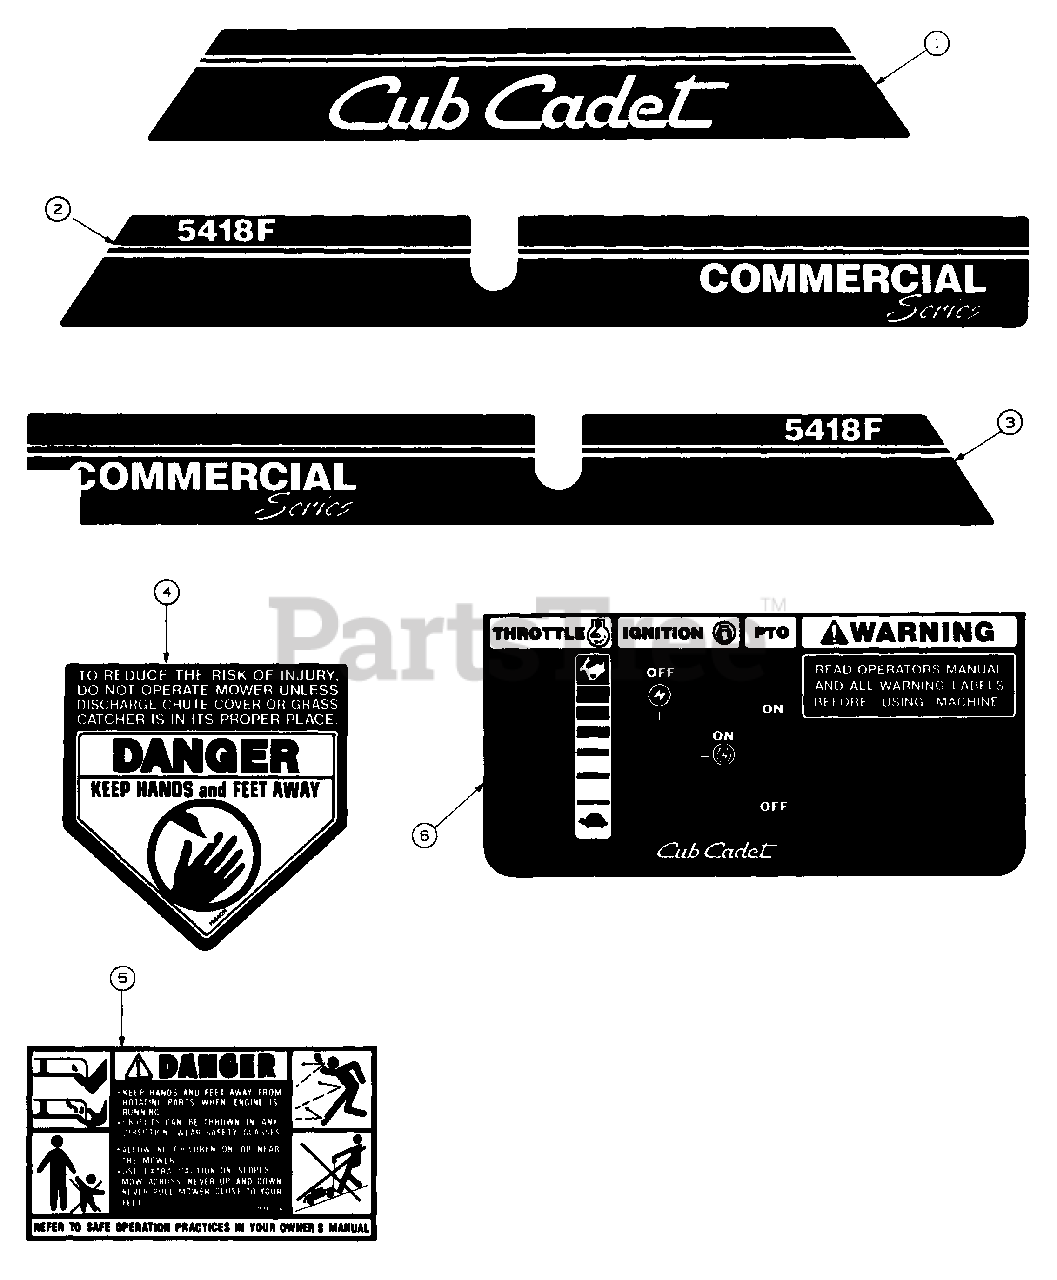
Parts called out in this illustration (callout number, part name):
1	Graphic, Belt Cover Front
2	Graphic 5418F, Belt Cover Right
3	Graphic 5418F, Belt Cover Left
4	Graphic, Danger Cut Finger
5	Graphic, Danger
6	Graphic, Control Panel
